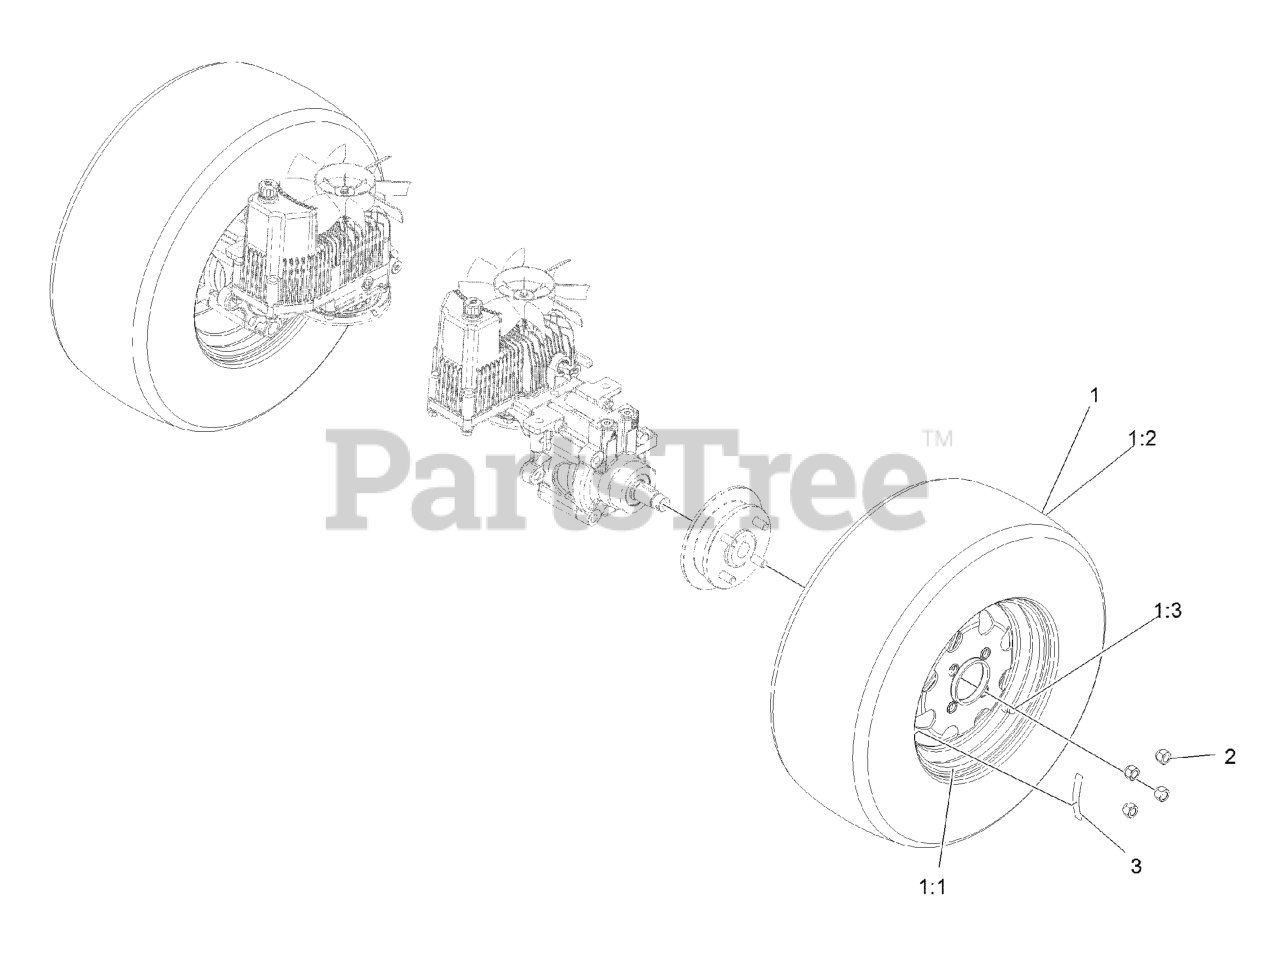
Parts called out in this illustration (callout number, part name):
1	WHEEL AND TIRE ASM
1:1	RIM ASM
1:2	TIRE
1:3	Stem-Valve
2	NUT-LUG
3	DECAL-TORQUE, WHEEL HUB LUG
